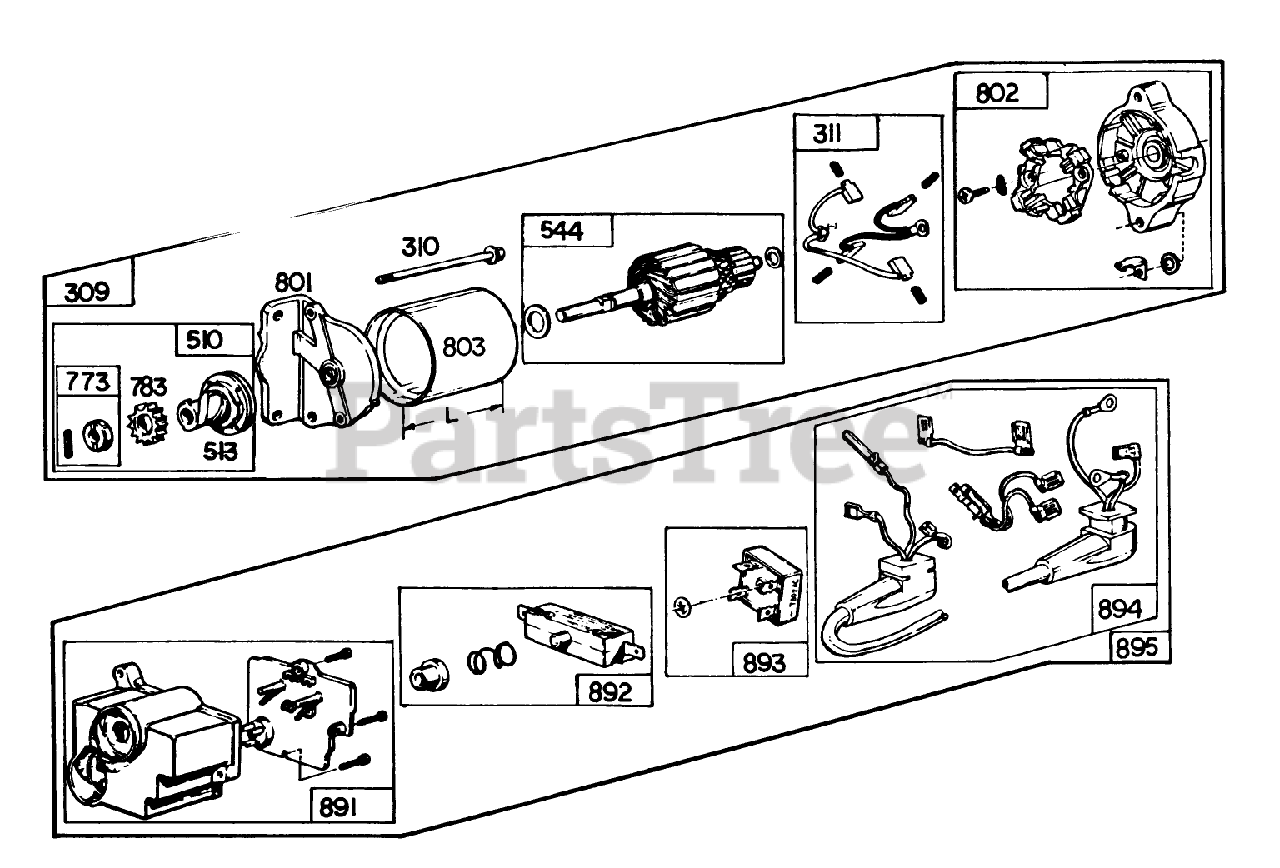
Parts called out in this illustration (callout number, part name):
309	Motor Drive Assembly
310	Thru Bolt Assembly
311	Brush Assembly
510	Drive Assembly
513	Clutch Assembly
544	Armature Assembly
773	Gear-Starter
801	Drive End Cap Assembly
802	Comm. End Cap Assembly
803	Housing Assembly
891	Housing Group
892	Switch Group
893	Rectifier
894	Lead Group
895	Control Group
